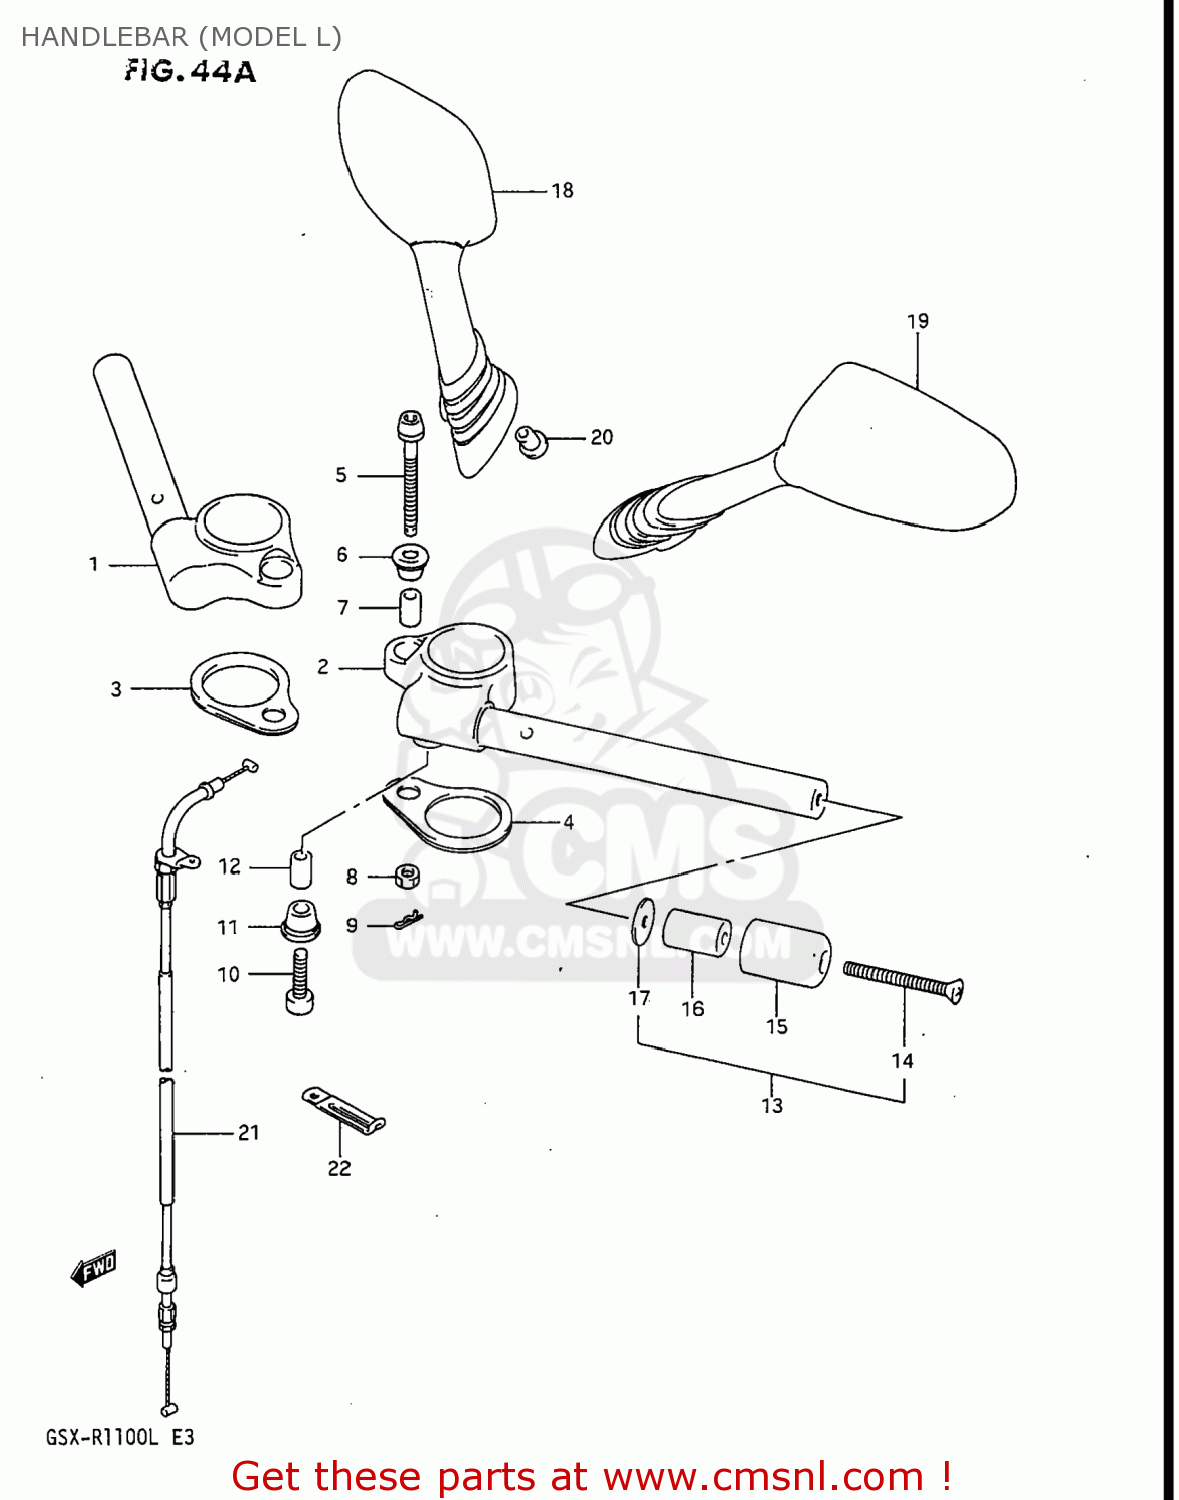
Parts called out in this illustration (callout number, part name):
1	HANDLEBAR,RIGHT
2	HANDLEBAR,LEFT
3	CUSHION,HANDLEBAR,R
4	CUSHION,HANDLEBAR,L
5	BOLT,HANDLEBAR
6	CUSHION,HANDLEBAR UPR
7	SPACER,HANDLEBAR
8	NUT 8MM
9	SNAP
10	BOLT, LH
11	CUSHION,HANDLEBAR UPR
12	SPACER,HANDLEBAR
13	BALANCER SET,HANDLEBAR
14	SCREW (L:65)(SUS)
15	CAP,BALANCER
16	BALANCER,HANDLEBAR
17	SPACER,BALANCER
18	MIRROR ASSY,RR VIEW,R
19	MIRROR ASSY,RR VIEW,L
20	NUT,RR VIEW MIRROR
21	CABLE ASSY,THROTTLE
22	CLAMP
